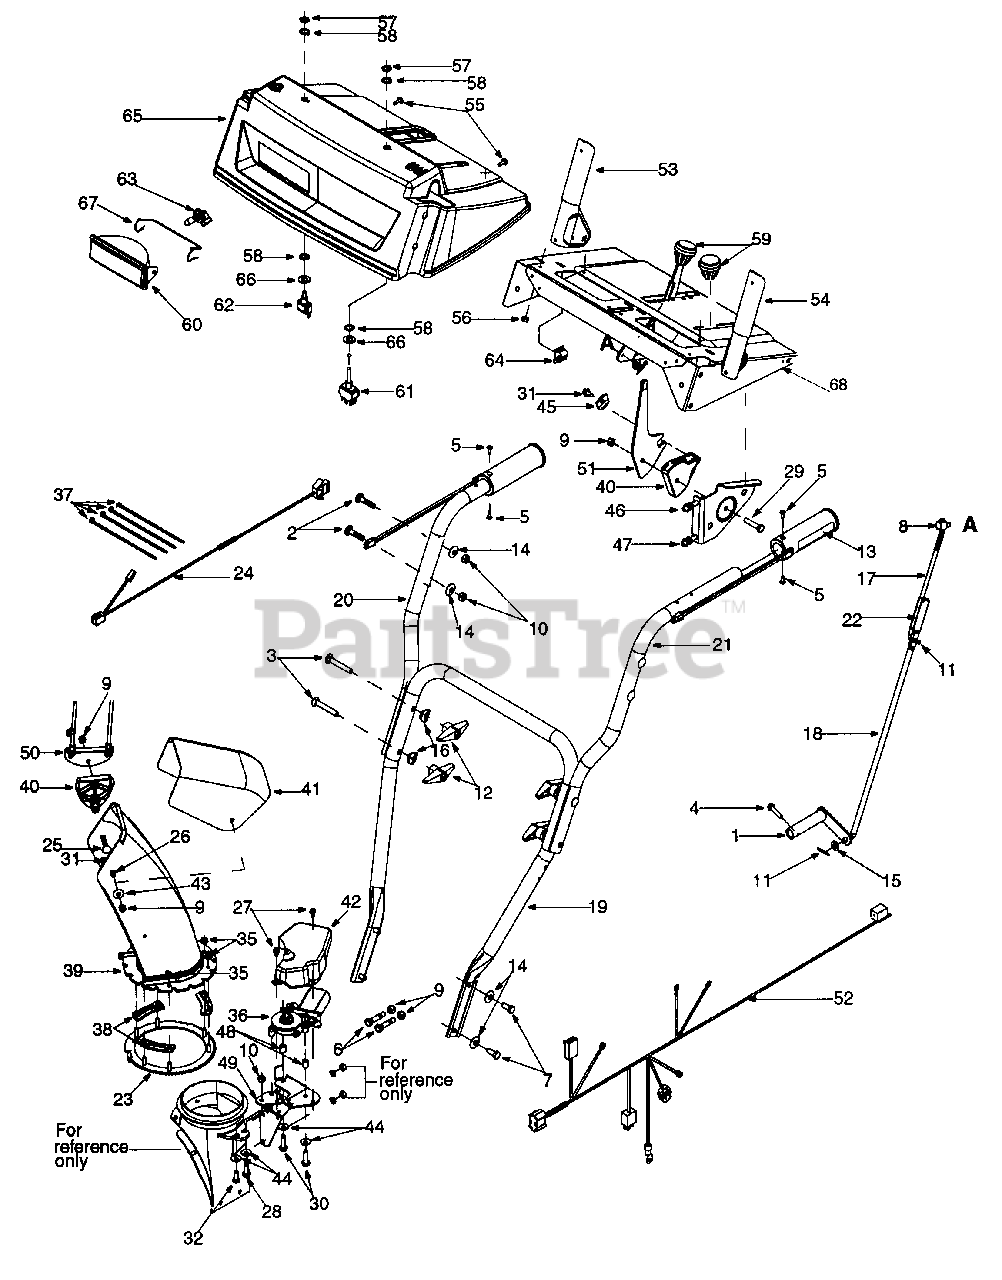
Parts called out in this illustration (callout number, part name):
1	Shift Arm Assembly
2	Carriage Bolt 5/16-18 x 1.5"
3	Carriage Bolt 5/16-18 x 2.25"
4	TT Screw 1/4-20 x 1"
5	Oval C-Sk. Screw AB #10-16 x 0.625"
6	Shear Bolt 5/16-18 x 1.5"
7	Hex Screw 5/16-18 x .75"
8	Ferrule
9	Hex Lock Nut 5/16-18
10	Hex Nut 5/16-18
11	Cotter Pin
12	Handle Knob
13	Heated Grip
14	Belleville Washer
15	Flat Washer
16	Saddle Washer
17	Shift Rod: Upper
18	Shift Rod: Lower
23	Gear Assembly: Ring
24	Electric Harness: Lower
25	Carriage Bolt: 5/16-18 x 1.5"
26	Carriage Bolt: 5/16-18 x .75"
27	TT Screw: 1/4-20 x 0.5"
28	TT Screw: 5/16-18 x 1"
29	Hex Screw: 5/16-18 x 1.5"
30	TT Screw: 5/16-18 x 1.25"
31	Hex Screw AB: 1/4-14 x 0.625"
32	Hex Screw: 5/16-18 x.75"
35	Hex Flange Lock Nut
36	Electric Motor: Chute Crank
37	Cable Tie
38	Chute Flange Keeper
39	Lower Chute
40	Cable Guide: Chute Tilt
41	Upper Chute
42	Motor Cover: Chute Rotation
43	5/16 Washer
44	Belleville Washer
45	Special Washer
46	Control Cable
47	Control Cable
48	Spacer
51	Handle: Chute Tilt
52	Harness Assembly: Upper
53	Handle Assembly RH: Engagement, Black
54	Handle Assembly LH: Engagement, Black
55	Special Hex Screw
56	Hex Sems Nut: 1/4-20
57	Hex Nut
58	Lock Ring: Toggle Switch
59	Shift Knob
60	Lamp Housing
61	Toggle Switch: Double Throw
62	Toggle Switch: Single Throw
63	Halogen Lamp: 50W, 12V
64	Mounting Clamp
65	Handle Panel Cover
66	Flat Washer
67	Headlight Retainer
